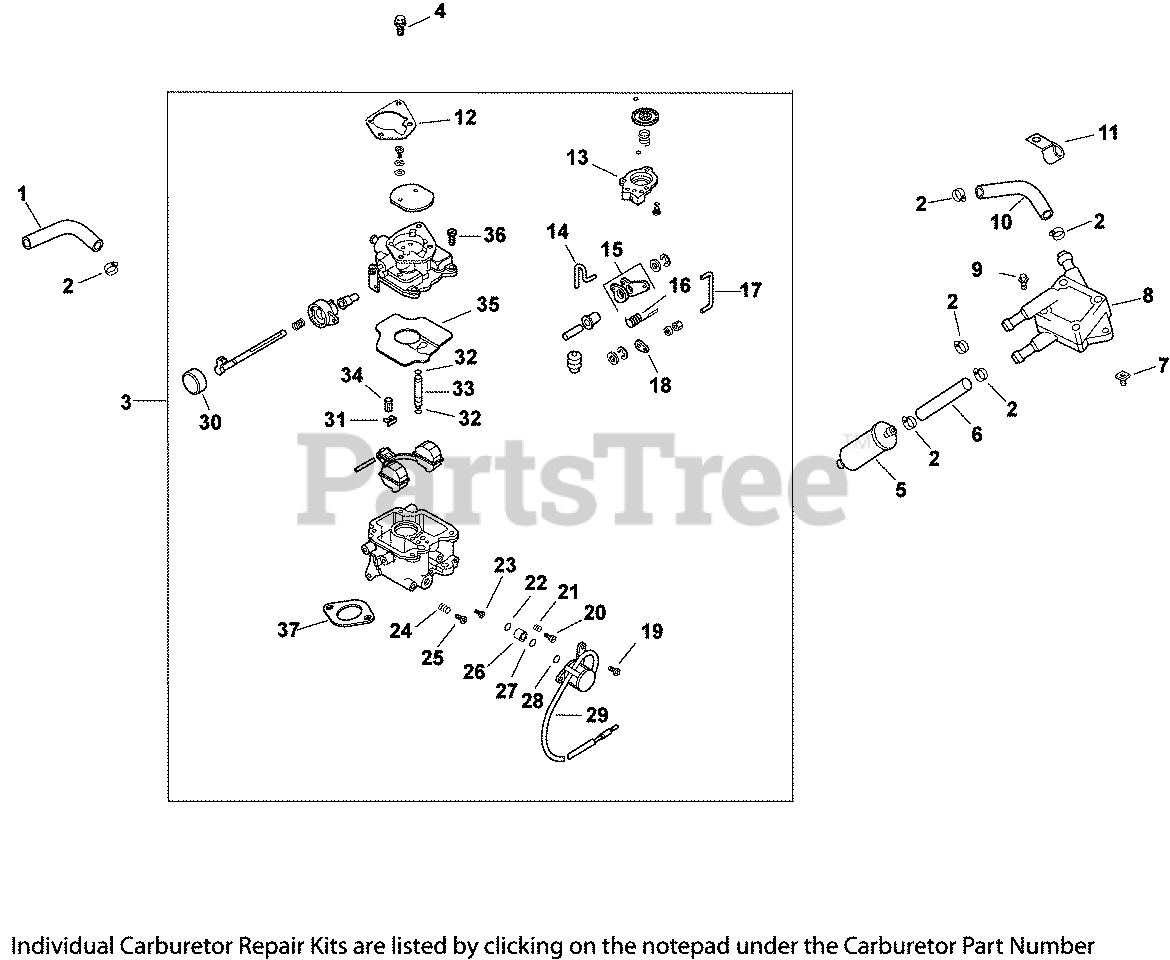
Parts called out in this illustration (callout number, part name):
1	LINE, FLEXIBLE FUEL 15 1/2"
2	CLAMP, HOSE (KM)-USE 25 237 31-S
3	KIT,CARB(KEIHIN) W/GASKETS-KSF
4	SCREW, FLNG THD FRM M6X1.0X10 USE 25 086 406-S
5	FILTER, FUEL
6	HOSE,LW PERM.FUEL 24.00"-USE 25 111 81-S
7	NUT, PLASTIC - BLACK
8	PUMP, FUEL
9	SCREW, TAP M6X1.7X18
10	SCREW, FLG M6X1.0X30
11	CLIP, CABLE
12	GASKET, AIR CLEANER BASE
13	HOUSING, PUMP
14	LINKAGE, ROD
15	LEVER, LINK
17	LINKAGE, ROD
18	LEVER, LINK
19	SCREW, SOLENOID
20	NEEDLE, IDLE
21	SPRING, IDLE NEEDLE
22	O-RING, SOLENOID
23	JET, MAIN
24	SPRING, IDLE SPEED ADJ SCREW
25	SCREW, IDLE
26	SEAT, SOLENOID
27	O-RING, SOLENOID
28	O-RING, SOLENOID
29	SOLENOID ASSEMBLY
30	CAP, CHOKE LEVER
31	CLIP, INLET NEEDLE VALVE
32	O-RING, SLOW JET
33	JET, SLOW
34	VALVE, INLET NEEDLE
35	GASKET, CARBURETOR BODY
36	SCREW, CARBURETOR BODY
37	GASKET, CARBURETOR
